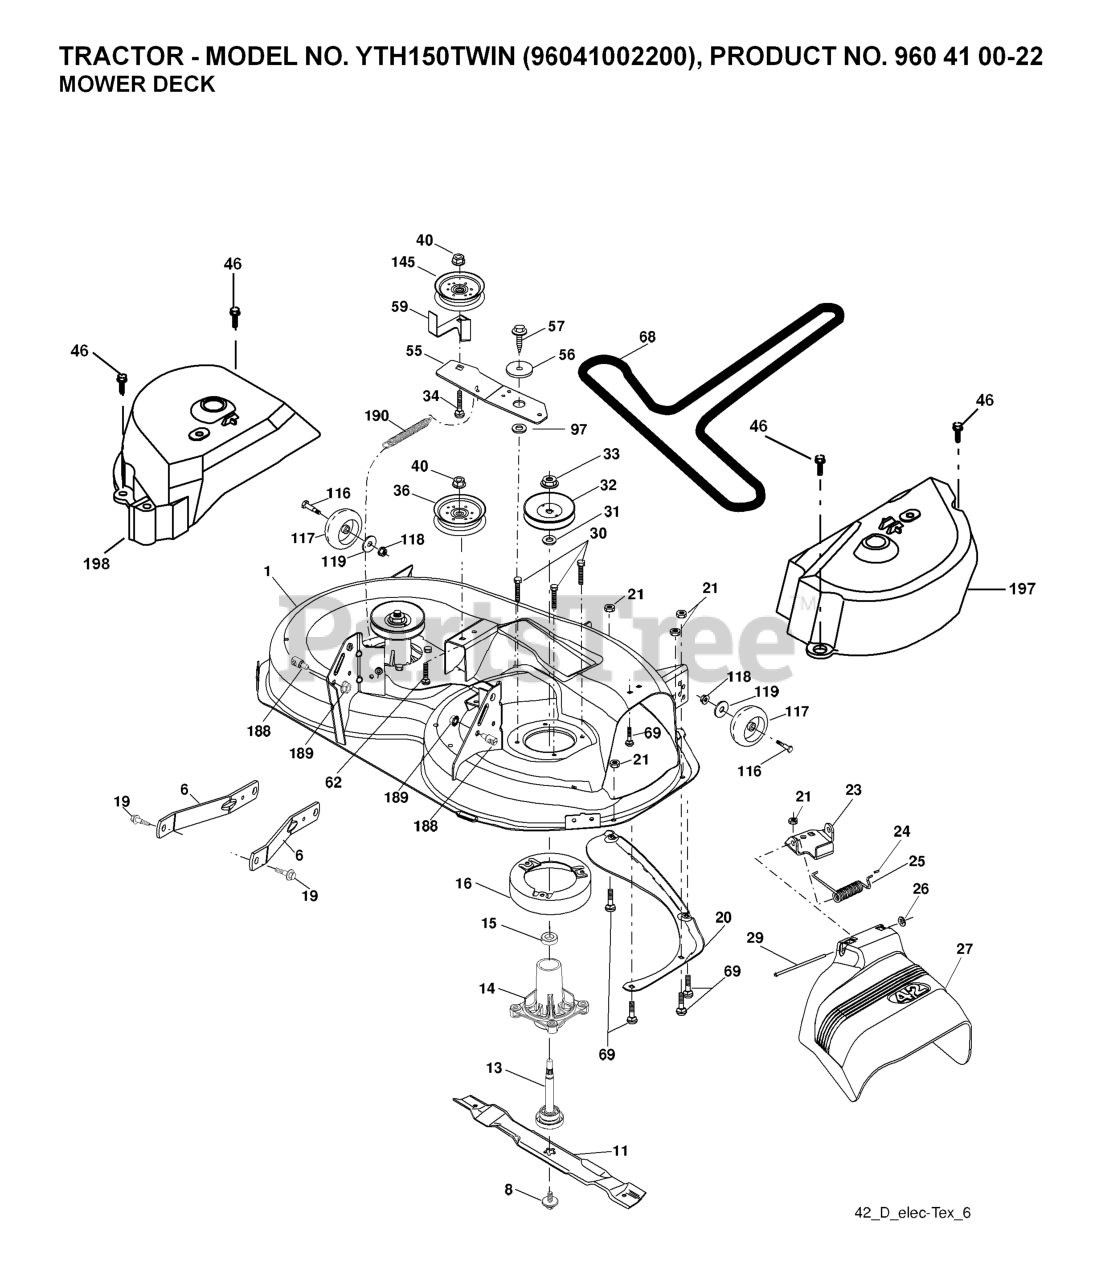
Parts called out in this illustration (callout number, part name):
1	DECK.WELDMENT.42"
6	ARM.SUSPENSION.MOWER.R
8	BOLT.WASHER.ASM.7/16-2
11	42" HI-LIFT BLADE
13	SHAFT.ASM.MDRL.N/GREASE.38
14	RP.HOUSING.MANDREL.4PT.
16	STRIPPER.MANDREL.ROUND.BLACK
19	BOLT.SHOULDER
20	BAFFLE.VORTEX
21	LOCKNUT
23	BRKT.DEFLECTOR.38"2005+
24	CAP-SLEEVE LT
25	SPRING.TORSION.DEFLECT
26	NUT PUSH M
27	DEFLECTOR ASM.42"TEX.FRENCH
29	ROD.HINGE
30	SCREW, WASHER HEAD
31	WASHER.SPACER.MANDREL
32	PULLEY/MANDREL
33	NUT.FLANGE.LOCK.TOP
34	BOLT.3/8-16X1.50
36	PULLEY.IDLER.2006
40	NUT LOCK FLG 3/8-16 UNC
46	SCREW.1/4-20X5/8
56	SPACER.RETAINER
57	SCREW 3/8-16X1
59	GUARD, BELT
68	BELT V SECONDARY
69	BOLT
116	BOLT M
117	WHEEL.GAGE.HALF.SPOKED
119	WASHER
145	PULLEY.IDLER.48"PRIMARY
188	STUD.FASTNER.W/ANTI-ROTATE
189	NUT LOCK HEX FLANGE 5/16-18
190	SPRING.MOWER.DRIVE.ELECTRIC
199	SCREW 3/8-16X1/2
